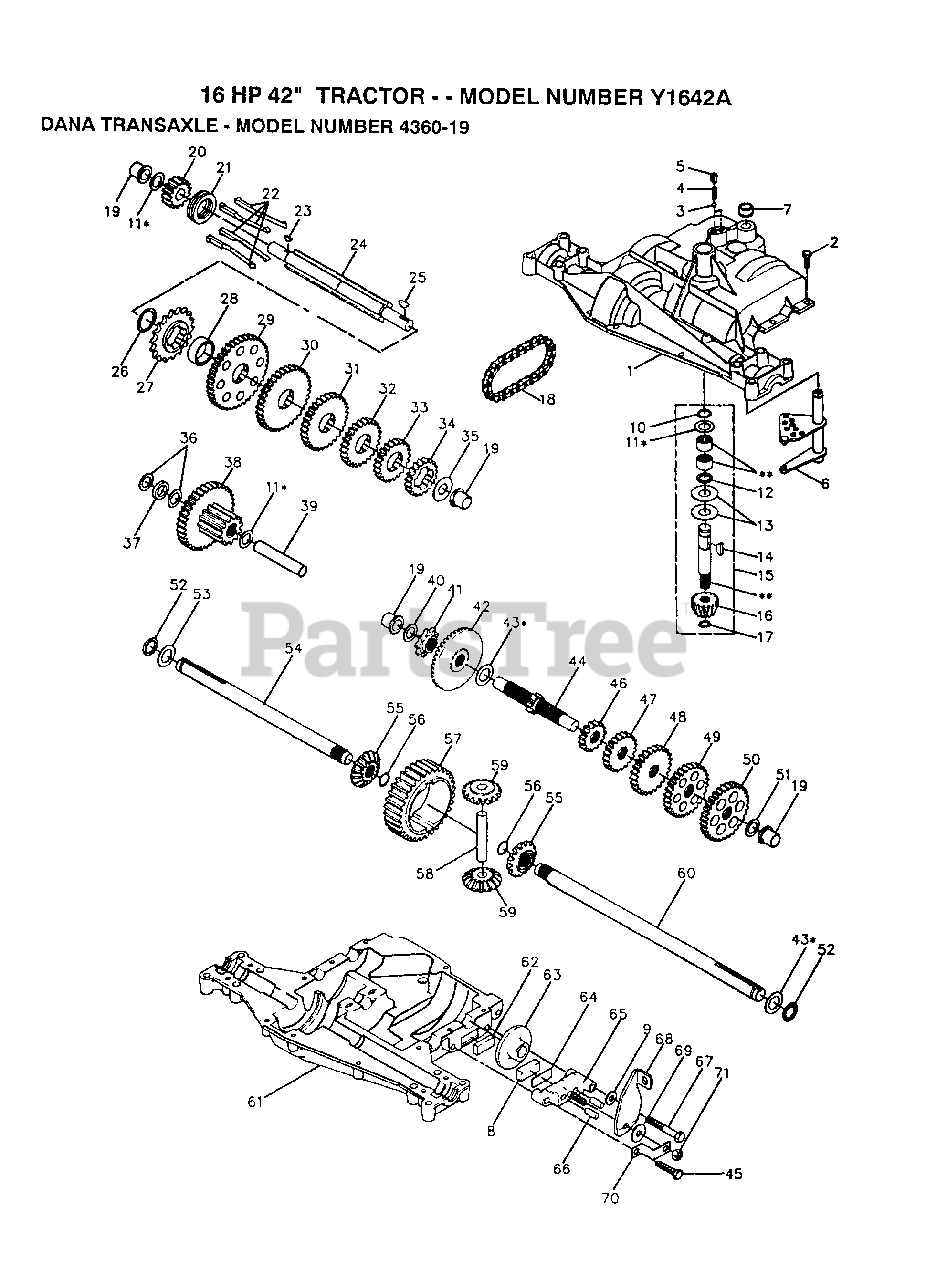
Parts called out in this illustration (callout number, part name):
1	HOUSING UPPER
3	BALL DETENT
4	SPRING, DETENT
5	SCREW, SET
6	ASSEMBLY, SHIFTER
8	PUCK, FRICTION
9	WASHER PLAIN
10	RING RETAINING
11	WASHER PLAIN
11A	WASHER PLAIN
11B	WASHER, PLAIN .632 X 1.00 X .026
11C	WASHER PLAIN
11D	WASHER PLAIN
11E	WASHER PLAIN
11F	WASHER PLAIN
11G	WASHER PLAIN
11H	WASHER, PLAIN .632 X 1.00 X .060
11I	WASHER PLAIN
13	WASHER, PLAIN .632 X 1.38 X .046
14	KEY WOODRUFF #9
15	ASSY KIT INPUT SHAFT
16	PINION BEVEL 14 TEETH
17	RING, RETAINING
18	CHAIN, 24 PITCHES
19	BEARING, FLANGE
20	GEAR, SPUR 14T
21	COLLAR CLUTCH
22	KEY CLUTCH
23	KEY WOODRUFF #3
25	KEY, WOODRUFF, #61
26	RING, RETAINING
27	SPROCKET, 18 TEETH
29	GEAR, SPUR 40T
30	GEAR, SPUR, 35 TEETH
31	GEAR, SPUR, 30 TEETH
32	GEAR, SPUR, 25 TEETH
33	GEAR, SPUR, 22 TEETH
35	WASHER, PLAIN .640 X 1.37 X .061
36	WASHER, PLAIN .632 X 1.00 X .026
37	SPACER .630 X 1.00 X .169
38	ASSY, GEAR, COMB., 12T & 35T
39	SHAFT, IDLER
41	SPROCKET, 9 TEETH
42	GEAR, BEVEL, 42 TEETH
43	WASHER PLAIN
43A	WASHER PLAIN
43B	WASHER PLAIN
43C	WASHER PLAIN
43D	WASHER PLAIN
43E	WASHER PLAIN
43F	WASHER, PLAIN .758 X 1.25 X .031
43G	WASHER PLAIN
43H	WASHER PLAIN
43I	WASHER PLAIN
43J	WASHER PLAIN
45	SCREW TAPPING
46	GEAR SPUR, 15 TEETH
47	GEAR, SPUR, 20 TEETH
48	GEAR, SPUR, 25 TEETH
49	GEAR, SPUR, 28 TEETH
50	GEAR, SPUR, 31 TEETH
51	WASHER, PLAIN .632 X 1.00 X .060
53	WASHER PLAIN
54	AXLE LEFT HAND
55	GEAR MITER 15 TEETH
56	RING, RETAINING
57	GEAR, SPUR, 32 TEETH
58	SHAFT, CROSS
59	GEAR, MITER, 15 TEETH
60	AXLE, R.H.
61	HOUSING LOWER
62	PUCK, FRICTION
63	DISC, BRAKE
65	JAW, BRAKE
66	PIN, DOWEL
67	SCREW TAPPING
68	LEVER, ACTUATING
69	WASHER, PLAIN .321 X 1.00 X .055
70	BRACKET, ANTI-ROTATION
71	LOCKNUT 5/16-24
